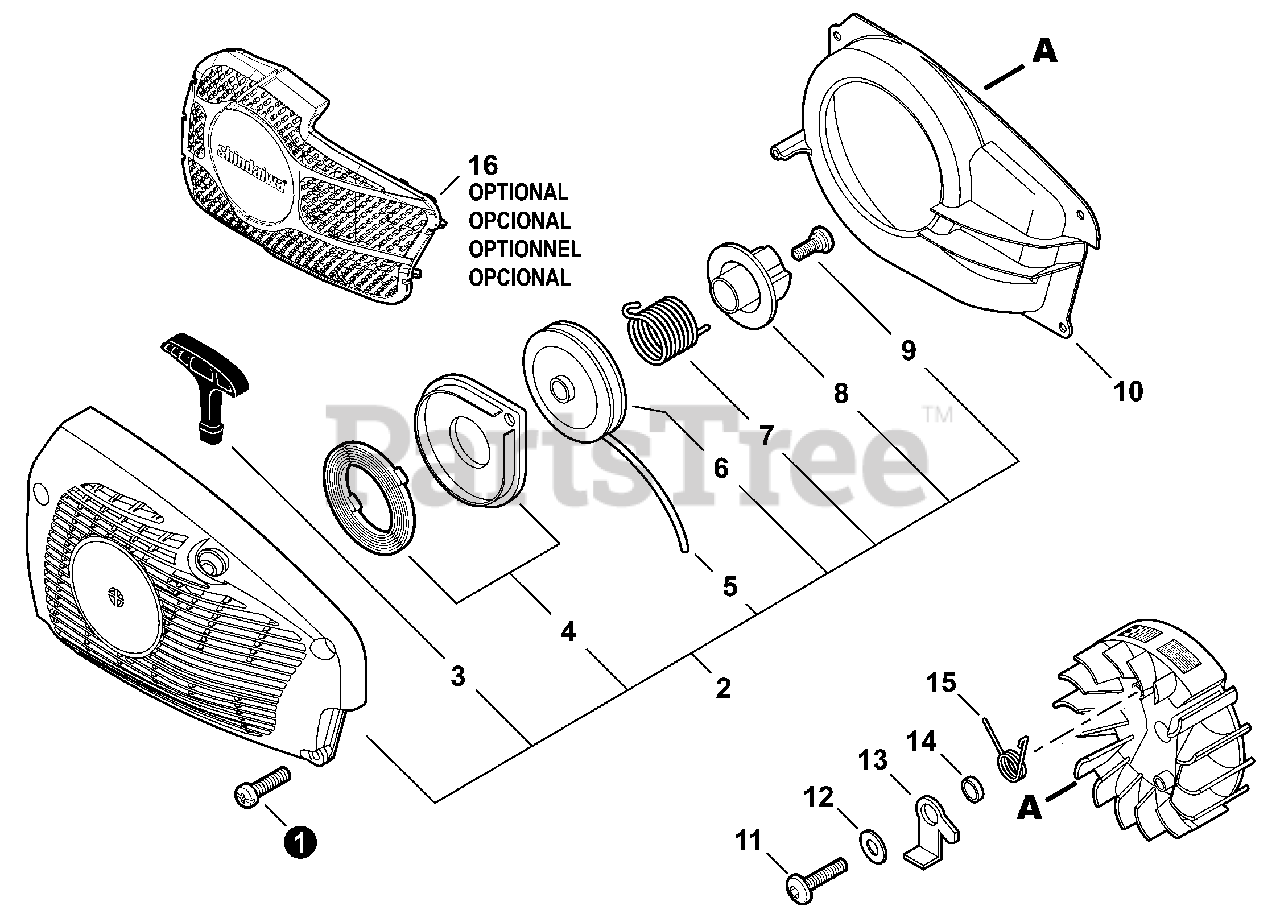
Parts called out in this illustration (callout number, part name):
1	BOLT, TORX 4×16
2	STARTER ASSY
3	GRIP, STARTER
4	SPRING KIT, RECOIL
5	ROPE, STARTER 3.5×900
6	REEL, ROPE
7	SPRING, RETURN
8	PLATE, CAM
9	SCREW
10	COVER, FAN
11	BOLT 5×14
12	WASHER 5.5×12×0.8
13	PAWL, STARTER
14	SPACER 5.2×8×2.1
15	SPRING, TORSION
16	SHIELD, DEBRIS
